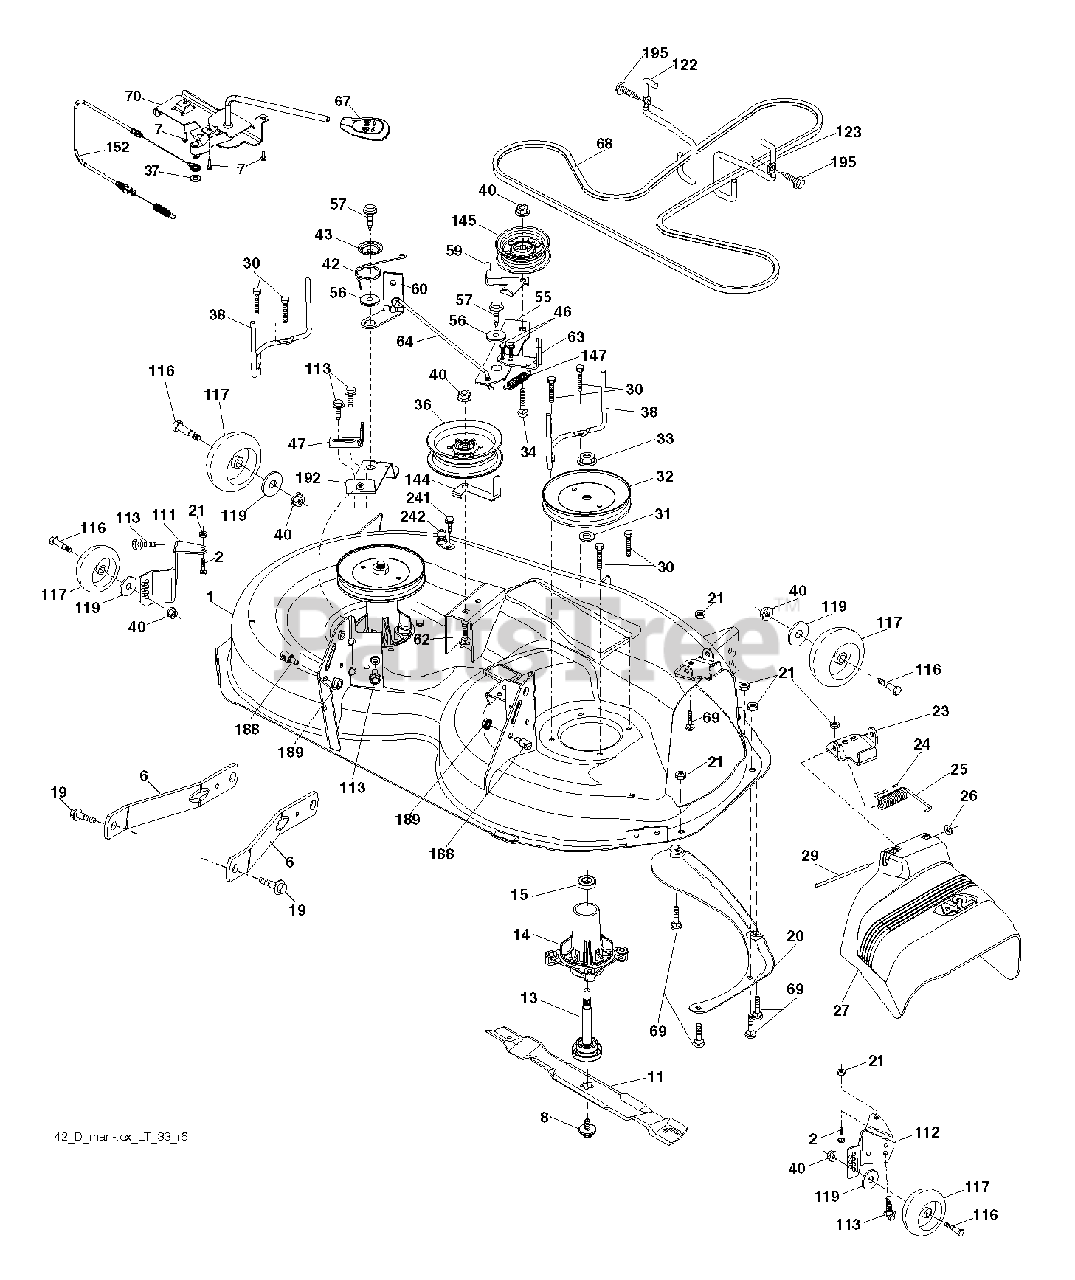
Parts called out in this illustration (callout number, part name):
2	BOLT
6	ARM.SUSPENSION.MOWER.R
7	SCREW.#10 X 0.750.BOS (2 2)
8	BOLT.WASHER.ASM.7/16-2
11	42" HI-LIFT BLADE
13	SHAFT.ASM.MDRL.N/GREASE.38
14	HOUSING.MANDREL.4PT.
19	BOLT.SHOULDER
20	BAFFLE.VORTEX
21	LOCKNUT
23	BRKT.DEFLECTOR.38"2005+
24	CAP-SLEEVE LT
25	SPRING.TORSION.DEFLECT
26	NUT PUSH M
27	SHIELD.DEFLECTOR.MOWER.42"BLAC
29	ROD.HINGE
30	SCREW, WASHER HEAD
31	WASHER.SPACER.MANDREL
32	PULLEY.MANDREL.5.438.PD
33	NUT.FLANGE.LOCK.TOP
34	BOLT.3/8-16X1.50
36	PULLEY.IDLER.2006
38	KEEPER.BELT.MANDREL.PULLEY
40	NUT LOCK FLG 3/8-16 UNC
42	SPRING.TORSION.BRAKE
43	SRPING.TORSION.RETAINE
46	SCREW.1/4-20X5/8
47	BRKT.CLUTCH.CABLE
55	IDLER.ARM.42"
56	SPACER.RETAINER
57	SCREW 3/8-16X1
59	GUARD, BELT
60	ARM BRAKE MOWER
62	BOLT
64	LINK BRAKE
67	HANDLE.CLUTCH.CABLE.LT
68	BELT.DECK.DRIVE.42"
69	BOLT
70	CLUTCH.ASM.MANUAL
111	BRKT.WHEEL.GAUGE.LH.42"
112	BRKT.WHEEL.GAUGE.RH.42"
113	BOLT.5/16HEX.WHS.HD
116	BOLT M
117	WHEEL.GAGE.HALF.SPOKED
119	WASHER
122	KEEPER BELT ENGINE LH
123	KEEPER BELT RH
144	KEEPER.BELT.MOWER
145	PULLEY.IDLER.48"PRIMARY
147	RETURN SPRING
152	CABLE.CLUTCH.MANUAL.
188	STUD.FASTNER.W/ANTI-ROTATE
189	NUT LOCK HEX FLANGE 5/16-18
192	BRKT.BRAKE.STAND.LH.
195	SCREW, 3/8-16X3/4
241	SCREW.TT.#10-32X.5.3/8.FLANGE
242	PORT.WASHOUT
